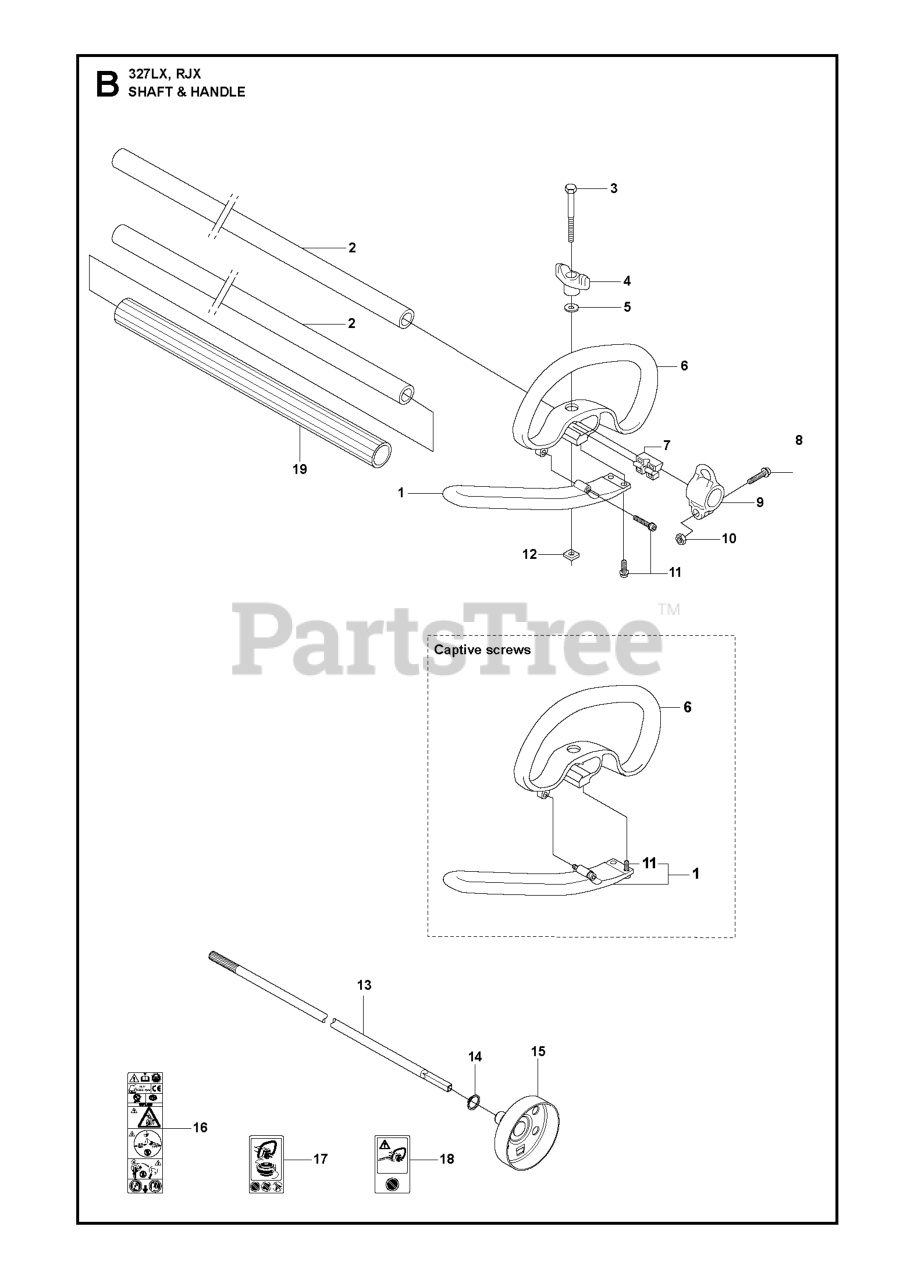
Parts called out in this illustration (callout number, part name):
1	HANDLE
1	HANDLE EXTENSION
2	DRIVE TUBE ASSEMBLY
2	TUBE DRIVESHAFT ASSY
3	SCREW
3	SCREW M6X50
4	KNOB
5	WASHER
6	HANDLE, LOOP
6	HANDLE
7	SPACER PLASTIC
8	SCREW
9	HARNESS HOLDER
10	NUT
11	SCREW
11	SCREW IHSCFTO
13	DRIVE SHAFT
14	RETAINING RING SGA 10
15	CLUTCH DRUM
16	RP WARNING DECAL
17	DECAL WARNING "NO BLADES"
18	DECAL
19	GRIP
